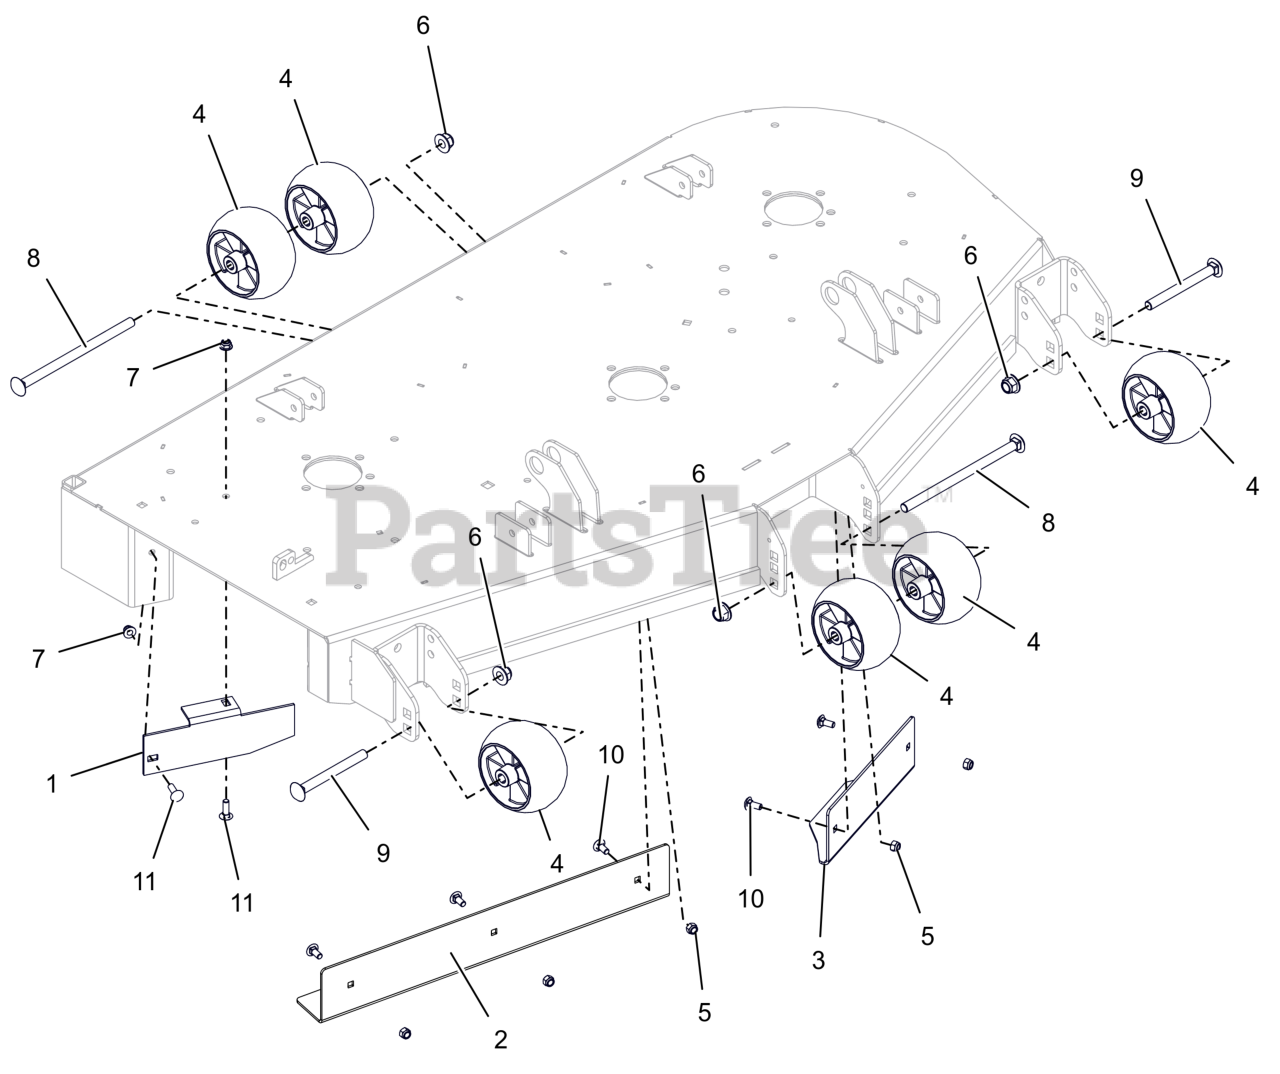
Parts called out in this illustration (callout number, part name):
1	BAFFLE, DISCHARGE, 52"
2	BAFFLE, 52" RH VACUUM (RED)
3	BAFFLE, 52" LH VACUUM (RED)
4	WHEEL, ANTI SCALP - 5X3 CTR W/RIBS
5	NUT,NYL .31-18 G5 ZCC
6	NUT,NYL-FLG .50-13 GF ZCC
7	NUT,NYL-FLG .31-18 GF ZCC
8	BTL,RHSN .500-13 X 8.5S G5 ZCC
9	BLT, RHSN .50-13X5.00 G5 ZCC
10	BLT,RHSN .31-18X.75 G5 ZCC
11	BLT,RHSN .31-18X1.00 G5 ZCC
